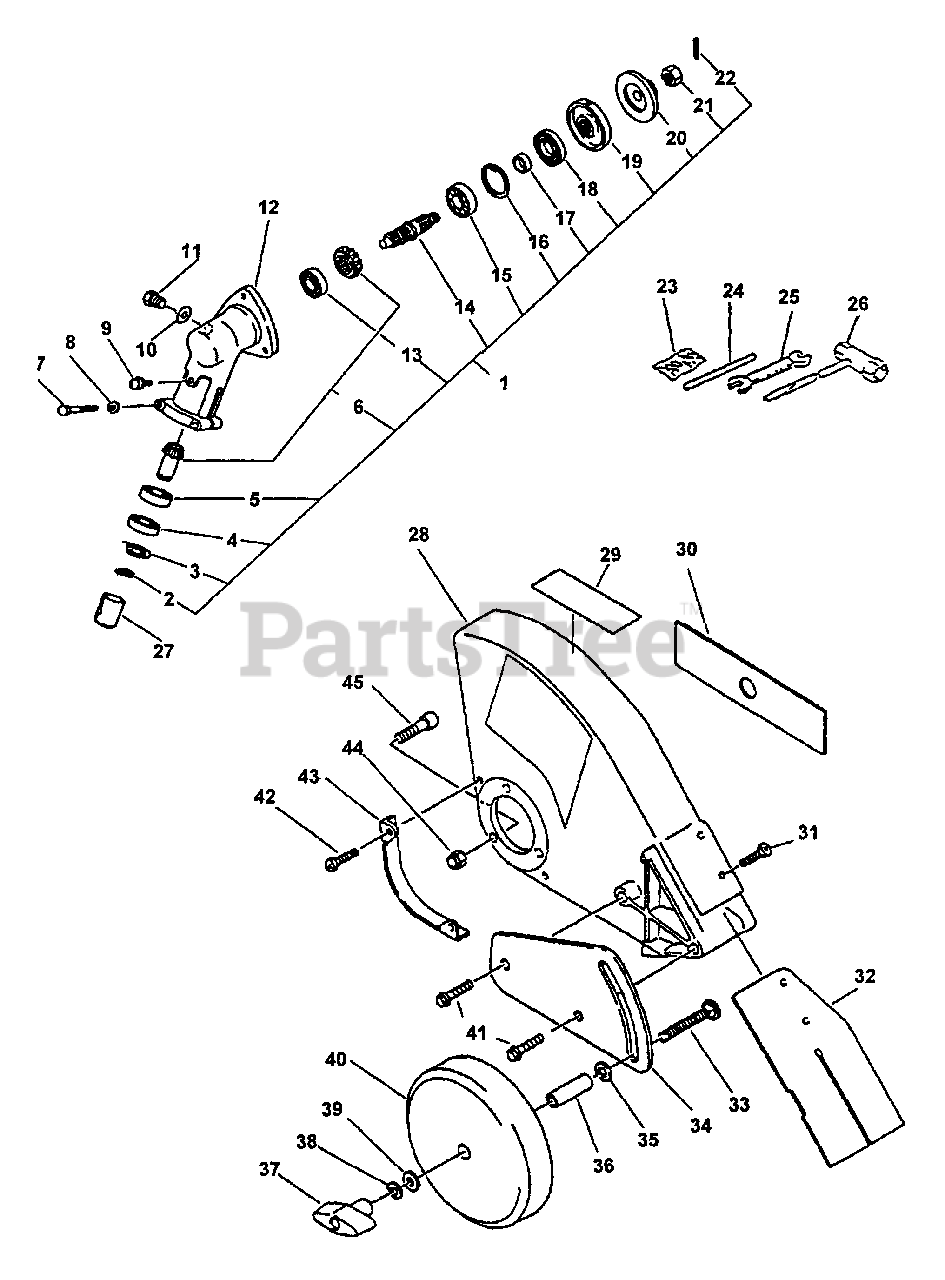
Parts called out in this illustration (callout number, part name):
1	GEAR CASE ASSY
2	RING, RETAINING - 18
3	RING, SNAP
4	BEARING, BALL 609ZZ
5	BEARING, BALL 609
6	GEAR SET
7	BOLT 5×30
8	WASHER, FLAT 5.5×10×0.8
9	SCREW 5×12
11	FITTING, GREASE
12	CASE, GEAR
13	BEARING, BALL 626
14	GEAR, SHAFT
15	BEARING, BALL 6201
16	RING, SNAP 20
17	COLLAR 10
18	SEAL, OIL
19	PLATE, ADAPTER - LOWER
20	PLATE, ADAPTOR - LOWER
22	PIN, COTTER 2×22
23	T-WRENCH 17x-19 L200
24	SPANNER 8×10
25	TOOL, LOCKING 5×120 MM
26	PIN, COTTER 2×22 (PKG. OF 10)
27	COLLAR
28	SHIELD, DEBRIS
29	LABEL, CAUTION
30	BLADE - 2 PK
32	FLAP, DEBRIS
33	BOLT 5/16"-18×2-1/2"
34	BRACKET, WHEEL
35	WASHER, SPRING 10
36	COLLAR 12
37	KNOB, FASTENER
38	WASHER, SPRING 8
40	WHEEL
43	GUARD, SHIELD
44	NUT, LOCK M5
45	BOLT 5×22
